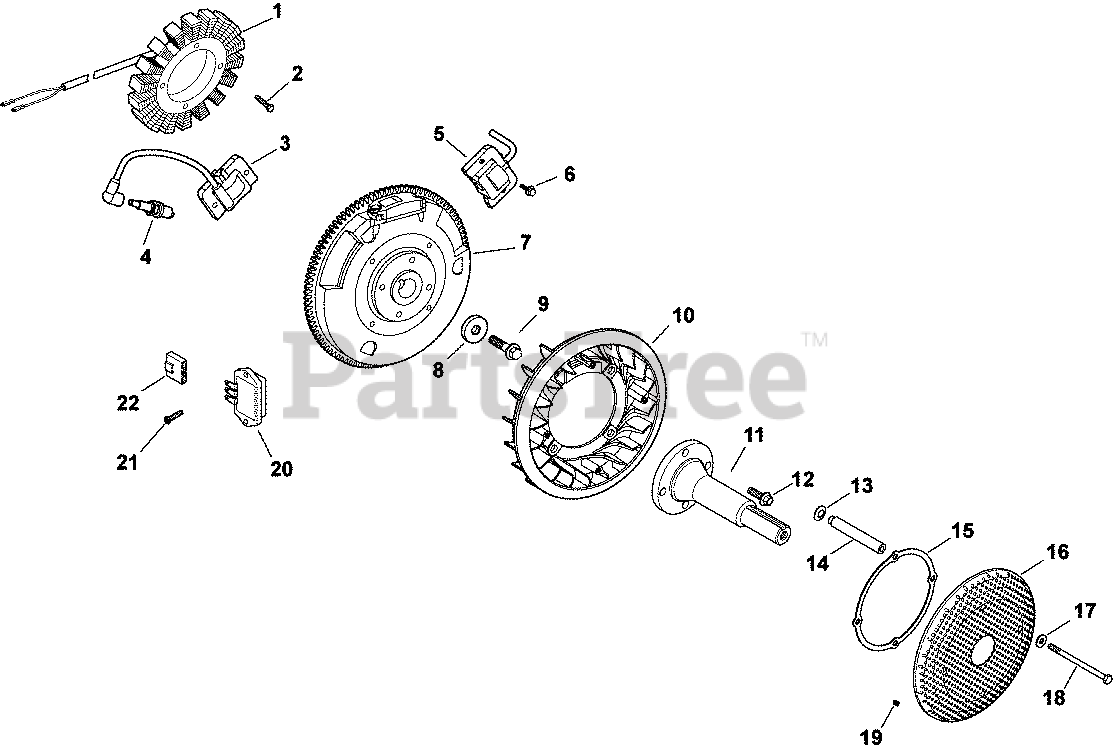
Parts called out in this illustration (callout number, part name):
1	KIT, 15 / 20 AMP STATOR
2	SCREW, M5X0.8X25 - (#25086402S)
3	MODULE, #2 CYLINDER-USE 66 584 09-S
4	PLUG, SPARK (STD)
5	MODULE, IGNITION - #1 CYLINDER-USE 24 58
6	SCREW, FLG THD FRM M5X.8X20-(#25086399S)
7	FLYWHEEL - (#DSC)
8	WASHER, FLAT 13/32"
9	SCREW, FLG M10X1.5X45 - (#25086361S)
10	FAN - (#DSC)
11	SHAFT, FRONT DRIVE
12	SCREW, FLG M8X1.25X25
13	WASHER, SPRING 10 MM
14	SPACER, GRASS SCREEN (#DSC)
15	RING, SUPPORT USE 25 141 08-S
16	SCREEN, GRASS
17	WASHER, FLAT 1/4" (O.D. 5/8")
18	SCREW, CAP M6X1.0X75 - DISCONTINUED
19	SCREW, SKT SET #10-24X1/4"
20	REG/RECT-15 AMP (KM)-USE 41 403 10-S
21	SCREW, PHL HD #11-16X7/8"
22	CONNECTOR, BODY (KM)-USE 25 155 41-S
